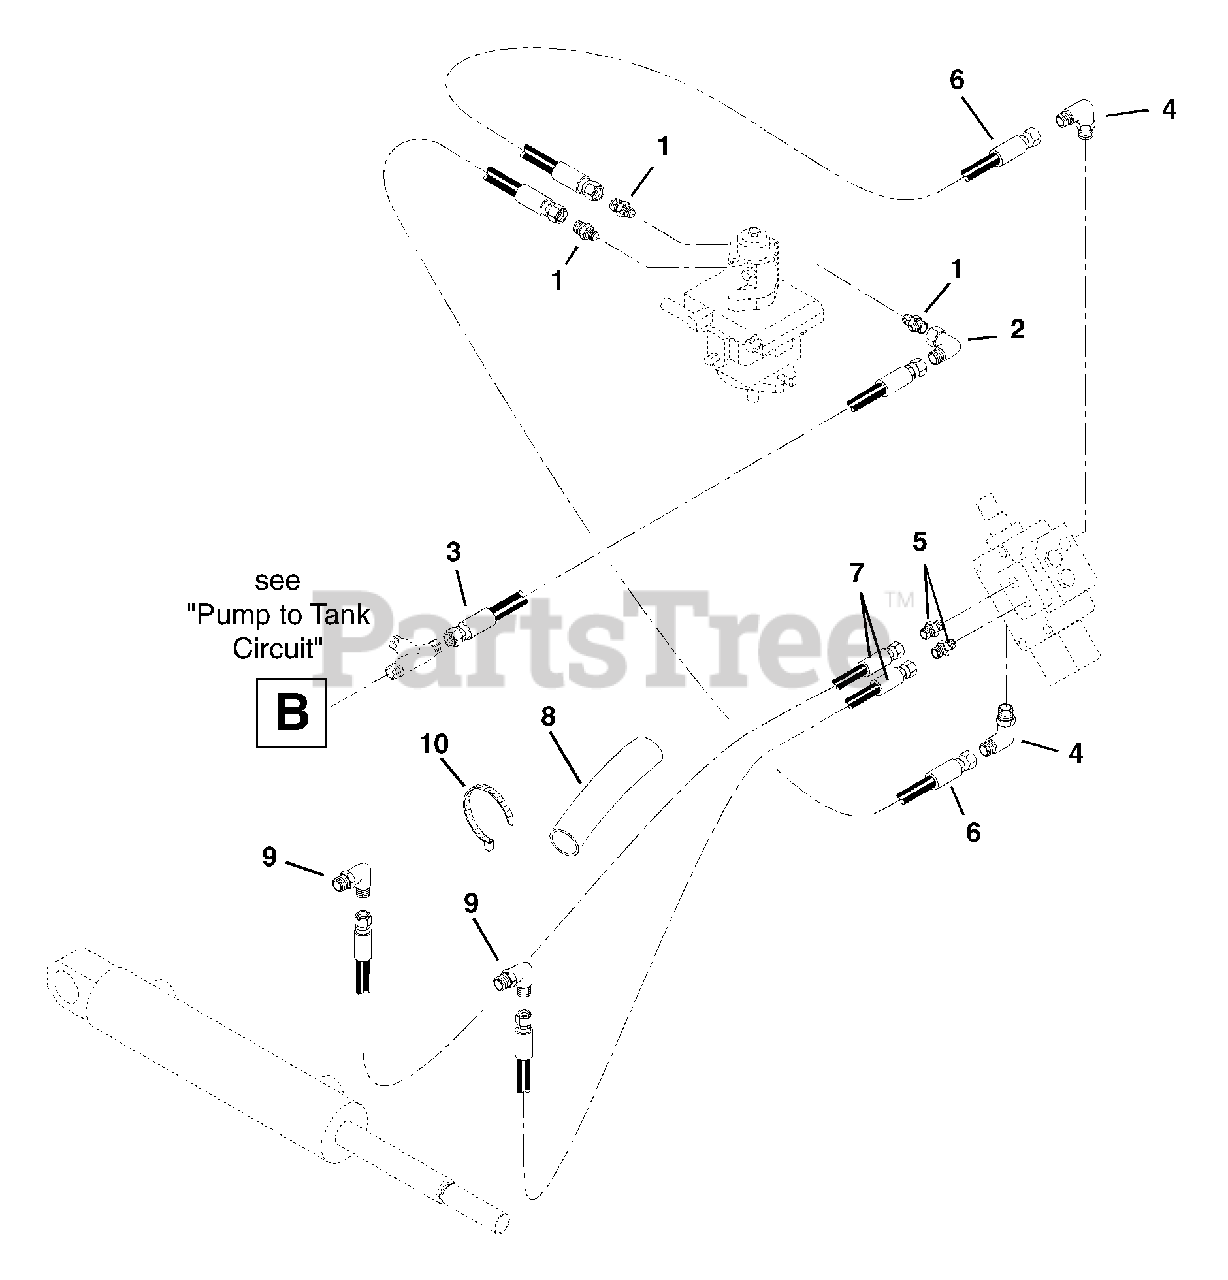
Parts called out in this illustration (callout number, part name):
2	Adapter
3	Hose-Hydraulic Valve to Tank
4	Adapter
5	Adapter
6	Hose Hydraulic .38 27.75 Long
7	Hose-Hydraulic .25 40.5" Long
8	Sleeve Protective 24"
9	Adapter
10	Cable Tie
